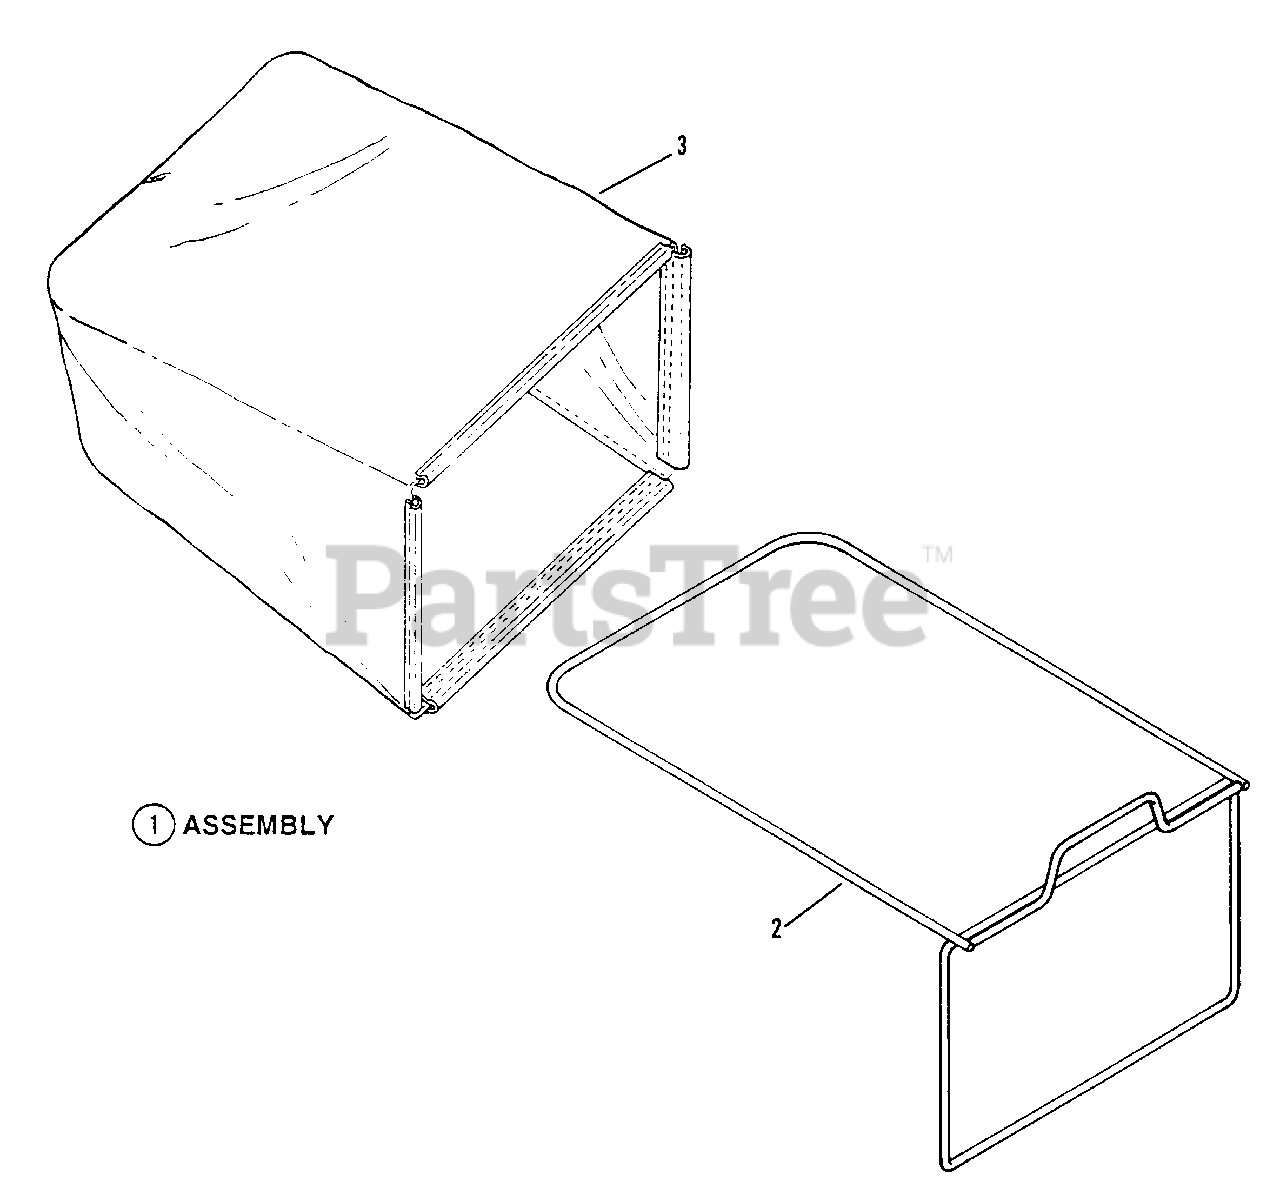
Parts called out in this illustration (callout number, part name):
1	KIT, Grass Bag
2	FRAME, Grass Bag
3	BAG, Grass
